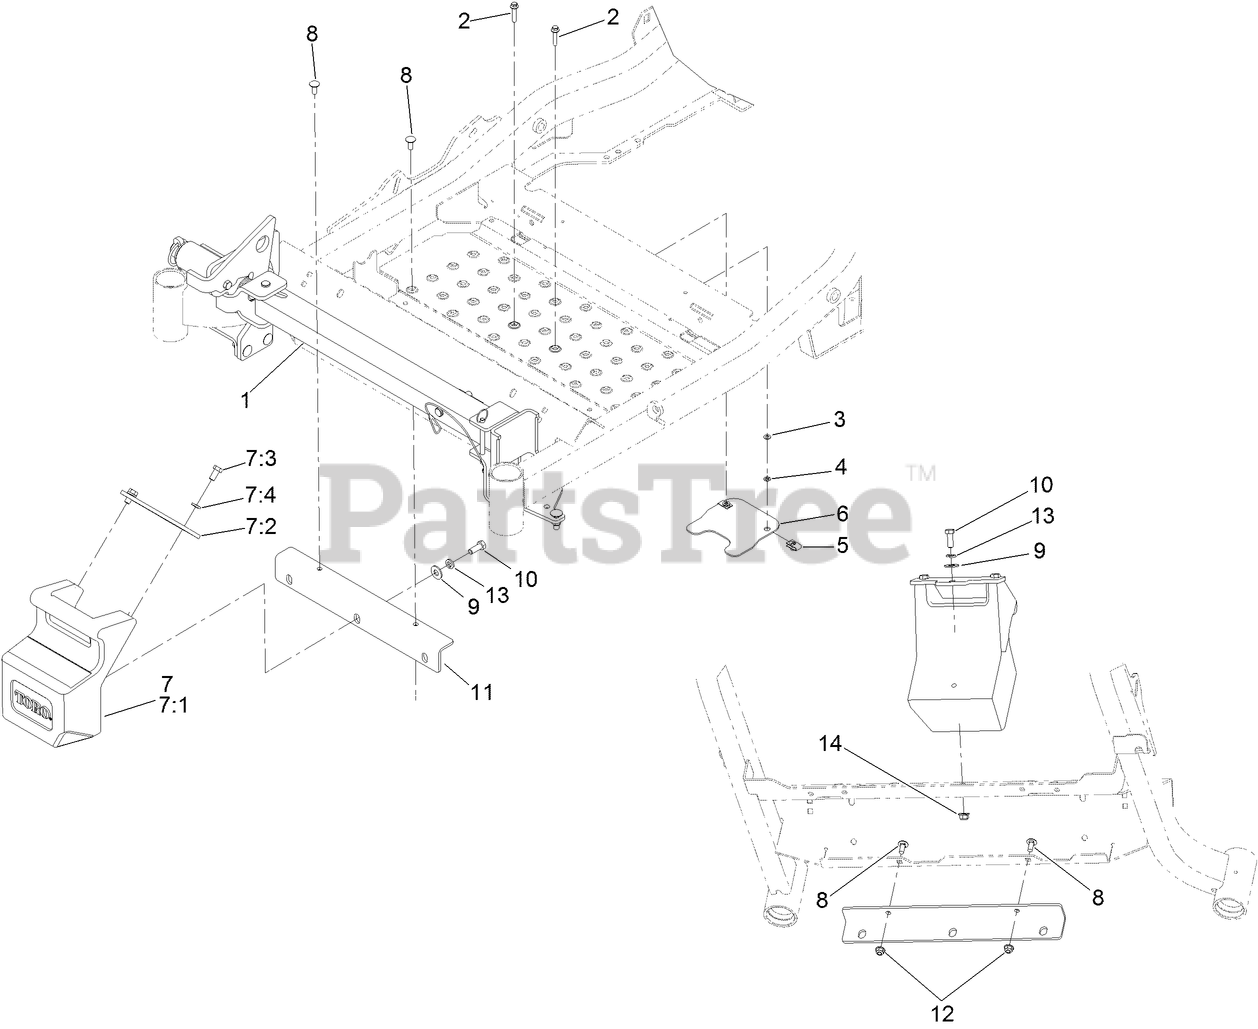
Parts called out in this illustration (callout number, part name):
1	KIT-Z STAND
2	SCREW-HHF
3	WASHER-FLAT
4	NUT-RETAINER
6	ADAPTER-CAPTIVE
7	WEIGHT ASM
7:1	WEIGHT-43 LB
7:2	TAB-SUPPORT, WEIGHT
7:3	SCREW-HH
7:4	SCREW-HH
8	SCREW-CARR
9	WASHER-FLAT
10	SCREW-HH
11	BRACKET-MOUNT, WEIGHT
12	NUT-HF, NI
13	SCREW-HH
14	NUT-HF, NI
